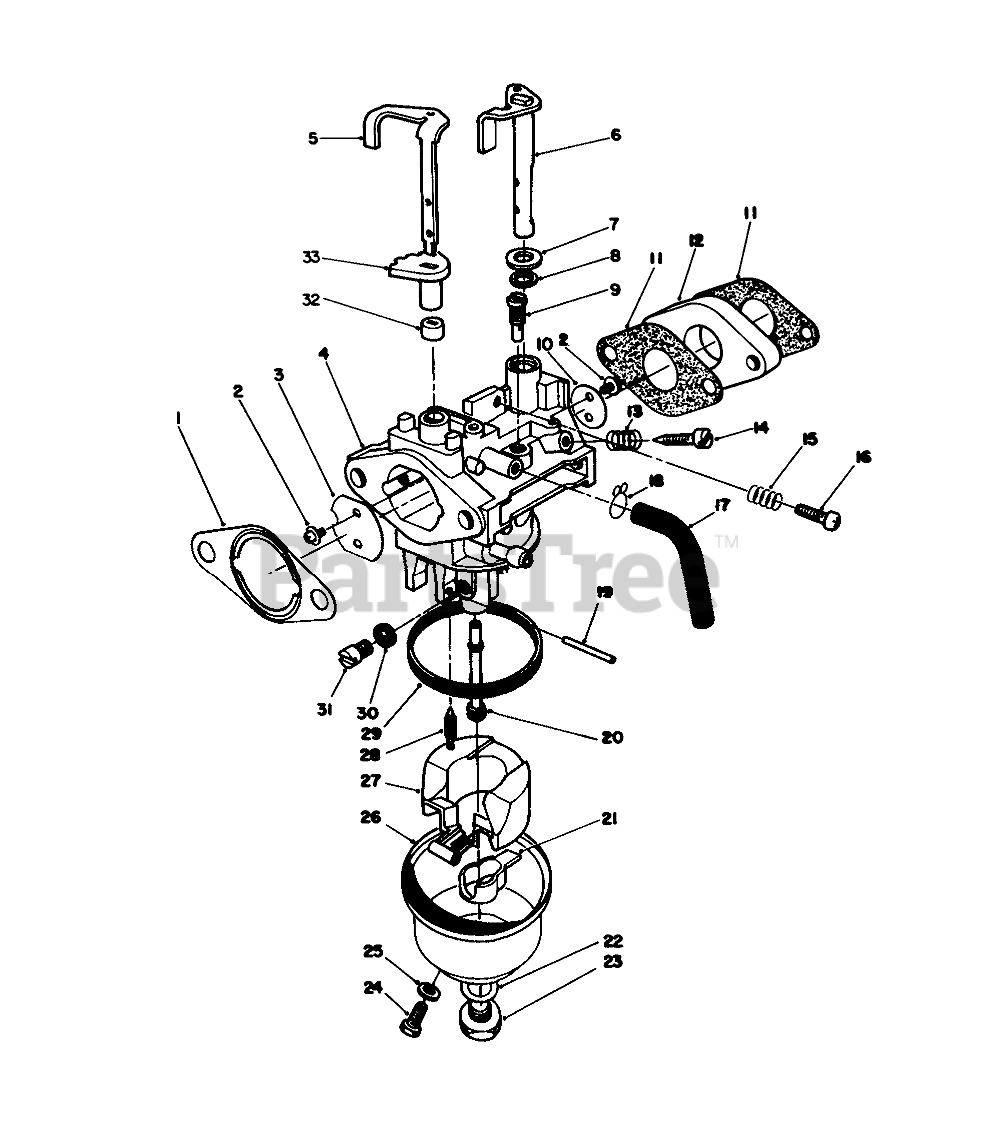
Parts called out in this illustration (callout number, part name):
1	GASKET F/W ENGINE
2	Screw
3	VALVE
4	Body-Carburetor
5	Shaft-Choke Valve
6	SHAFT
7	WASHER
8	Seal-Throttle Shaft
9	PILOT JET
10	VALVE
11	Gasket-Carburetor
12	CARB INSULATOR
13	SPRING-PILOT SCREW
14	ADJUSTER
15	Spring-Idle Stop
16	SCREW
18	CLAMP
19	Pin
20	NOZZLE
21	SPACER
22	GASKET
23	SCREW
24	SCREW
25	GASKET
27	FLOAT
28	NEEDLE
29	FLOAT BOWL GASKET
30	SPACER
31	MAIN JET
32	LOWER CHOKE RING
33	UPPER CHOKE RING
